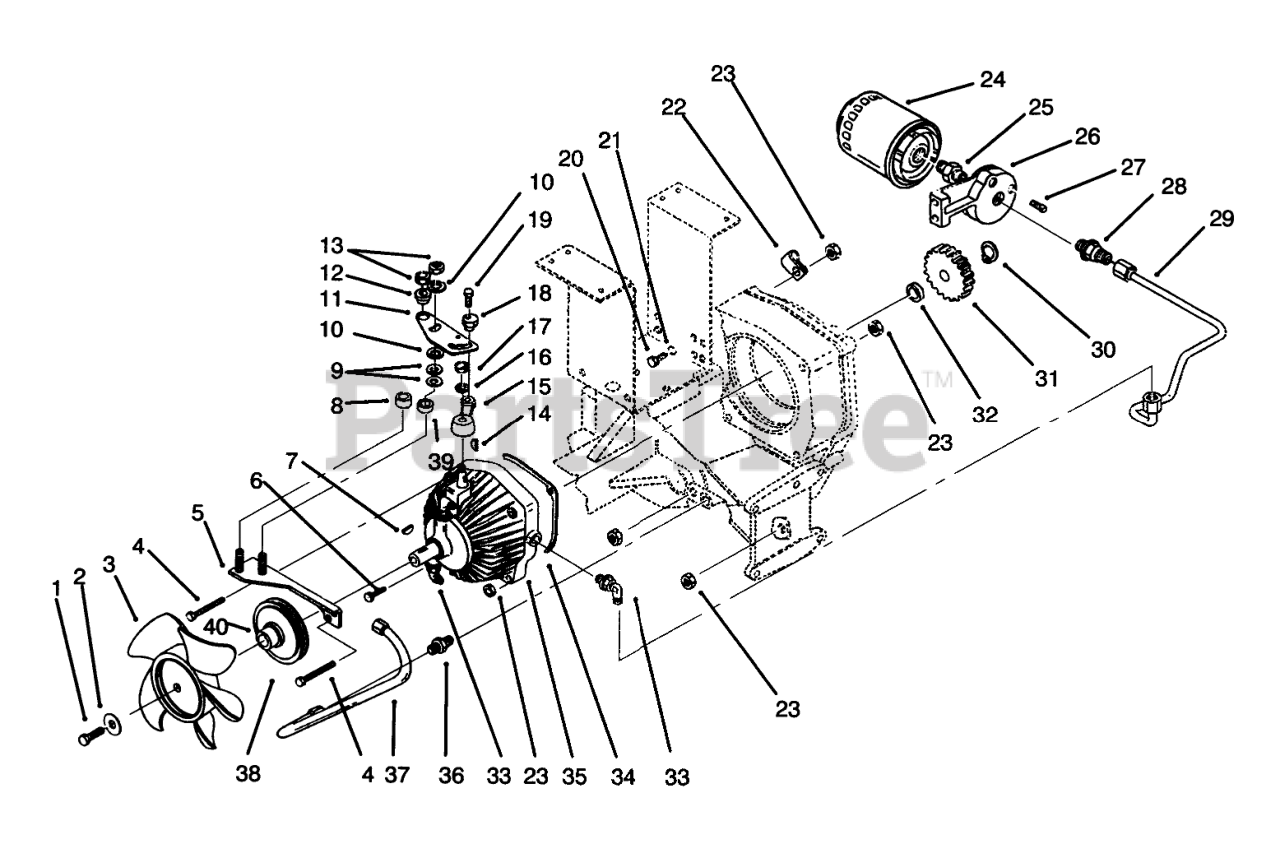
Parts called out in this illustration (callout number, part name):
1	SCREW-HEX HD CAP
2	WASHER
3	NYLON FAN-L-CW
4	SCREW-HH
5	ASSY-PLATE B
7	KEY-WOODRUFF
8	SPACER-PIVOT
9	WASHER-SPRING DISC
10	FRICTION WASHER
11	CAM-SPEED CONTROL (NS)
12	CAM-SPACER
14	KEY-WOODRUFF
15	ARM-SPEED CONTROLB
16	WASHER-FLAT
17	NUT-LOCK, NI
19	Screw-HH
20	SCREW-HH
21	WASHER-LOCK
22	CLIP
23	NUT-LOCK, NI
24	OIL FILTER ASM
25	FITTING
26	BASE-FILTER
28	Fitting-Hyd., Straight (Incl. "O"Ring)
29	ASS'Y-TUBE FILTER
30	RING-SNAP, EXTERNAL
31	GEAR 20 TEETH DRIVE
32	SPACER GEAR
33	ELBOW
34	GASKET
35	Pump & Motor
36	FITTING-TUBE
37	ASSY-TUBE SUCTION
38	PULLEY
39	SPACER-FRICTION
